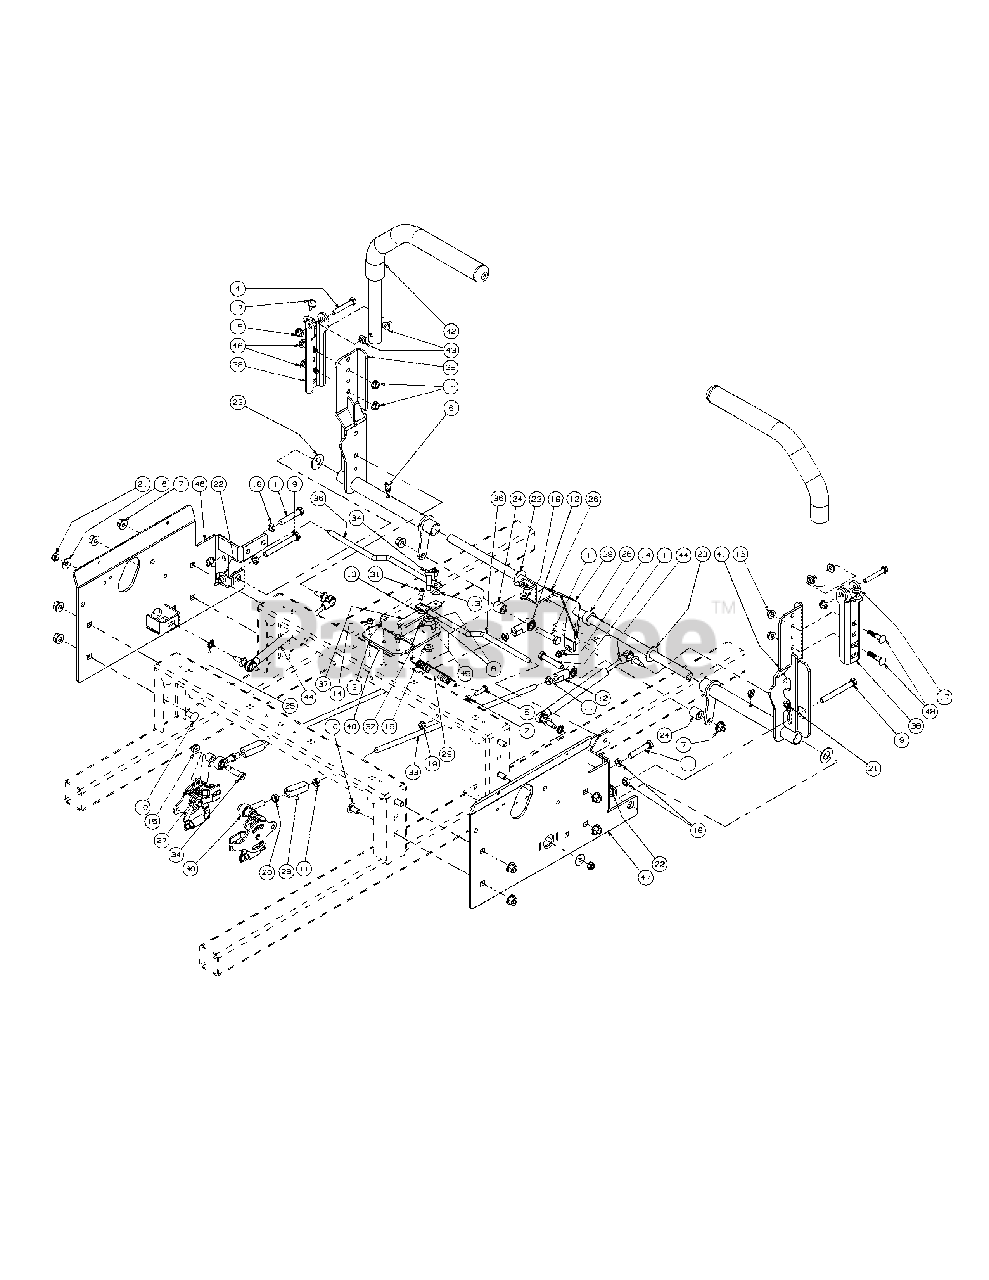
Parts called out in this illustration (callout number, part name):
1	Hex Cap Screw, 3/8-16 x 2.00
2	Hex Nut, 1/4-20
3	Hex Cap Screw, 1/4-20, .75
4	Hex Cap Screw, 5/16-18 x 2.00
5	HHCS, 1/4-20 x 1.00
6	Grease Fitting, 1/4-28, 45 degree
7	Hex Nut, 3/8-16, Lock Flange
8	Washer, 3/8, SS
9	Hex Cap Screw, 3/8-16 x 3.50
10	Carriage Bolt, 3/8-16 x .75
11	Hex Jam Nut, 3/8-24
12	B/Joint, 3/8-24, Right Hand Female
13	Flat Washer, 1.4 x .630 x .0515
14	Screw, TT, 1/4-20, 0.5, Hex Index Washer
15	Nut, Lock, HexFlange, 5/16-18
16	Belle Washer, .325 x .930 x .045
17	Rubber Bumper, .62 OD x .22 Thick
18	Nut, 3/8-16, Jam
19	Hex Flange Lock Nut, 1/4-20
20	Nut, 3/8-24, Jam, LH Third
21	Nut, Hex, Center Lock, M8
22	U-Nut, 3/8-16, .75
23	Flat Washer, 5/8 Nylon
24	Spacer, .385 ID x .75 OD x .875
25	External Washer, 3/8
26	Shaft Collar
27	Spacer, .625 OD x .385 ID x 1/2
28	Turnbuckle
29	Extension Spring, .53 OD x 4.75
30	B/Joint, 3/8-24, Left Hand Female
31	Shoulder Bolt, 1/4 x 1/4
32	Nut w/ Star Washer, 10-24
33	Control Rod, 3/8 x 17.312
34	Screw, Shoulder Control Rod
36	Brake/Control Rod
37	Lapbar Control Arm
38	Lapbar Pivot Bracket
39	Lapbar Control Shaft Assembly
40	Lapbar/Brake Control Mounting Bracket
42	Lapbar Assembly includes:
43	Bushing, .310 x .172 x .688 x .06
44	Cylinder Return to Neutral
45	Spacer, .405 ID x 1.0 OD x .72
46	Side Panel, Control, Left
47	Side Panel, Control, Right
48	Carriage Bolt, 5/16-18 x 1.50
